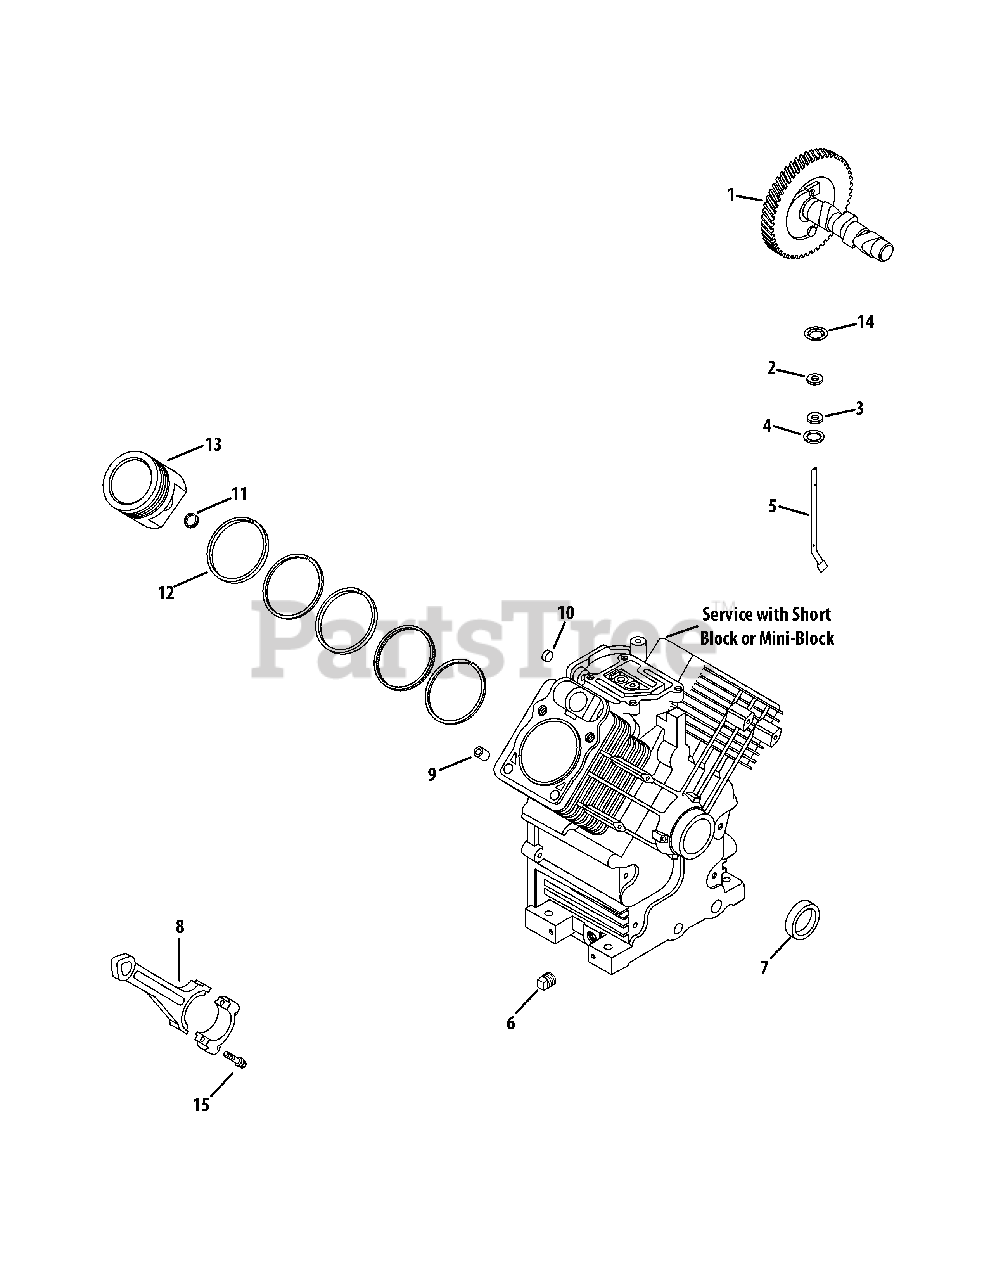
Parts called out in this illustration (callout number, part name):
1	Camshaft Kit
2	Flat Washer, 9 MM
3	Governor Cross Shaft Seal
4	Flat Washer, 11/32
5	Governor Cross Shaft
6	Square Headd Pipe Plug, 3/8
7	Oil Seal (Helix Lip)
8	Connecting Rod Assembly
11	Piston Pin Retainer
12	Ring Set (Std)
12	Ring Set (.08)
12	Ring Set (.25)
12	Ring Set (.50)
13	Piston Kit w/ Ring Set (Standard)
13	Piston Kit w/ Ring Set (.08)
13	Piston Kit w/Ring Set (.25)
13	Piston Kit w/ Ring Set (.50)
14	Ring Retainer
15	Rod Bolts Kit
